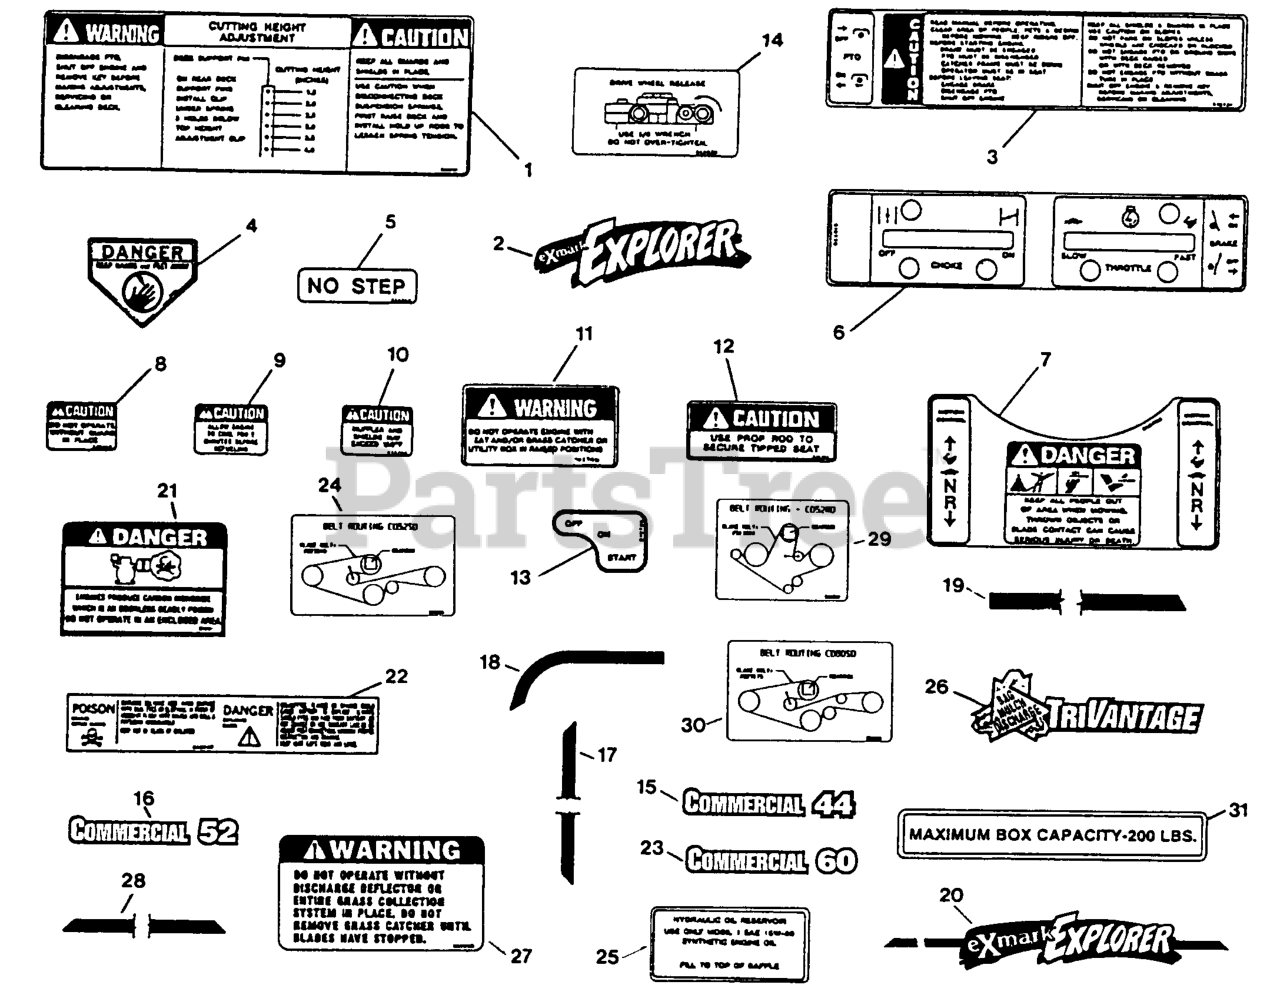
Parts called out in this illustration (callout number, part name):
2	DECAL,EXMARK EXPLORE
3	DECAL,FENDER RH
4	DECAL-DANGER
5	DECAL,NO STEP
7	DECAL,CONSOLE
8	DECAL-GUARD
15	DECAL,COMMERCIAL 44
16	DECAL,COMMERCIAL 52
17	DECAL,CATCHER FRONT
18	DECAL,LH CATCHER STR
22	DECAL-BATTERY
23	DECAL,COMMERCIAL 60
24	DECAL,BELT RTNG CD52SD
25	DECAL,HYD TANK
27	DECAL-WARNING, DISCHARGE
29	DECAL,BELT RTNG CD52RD
